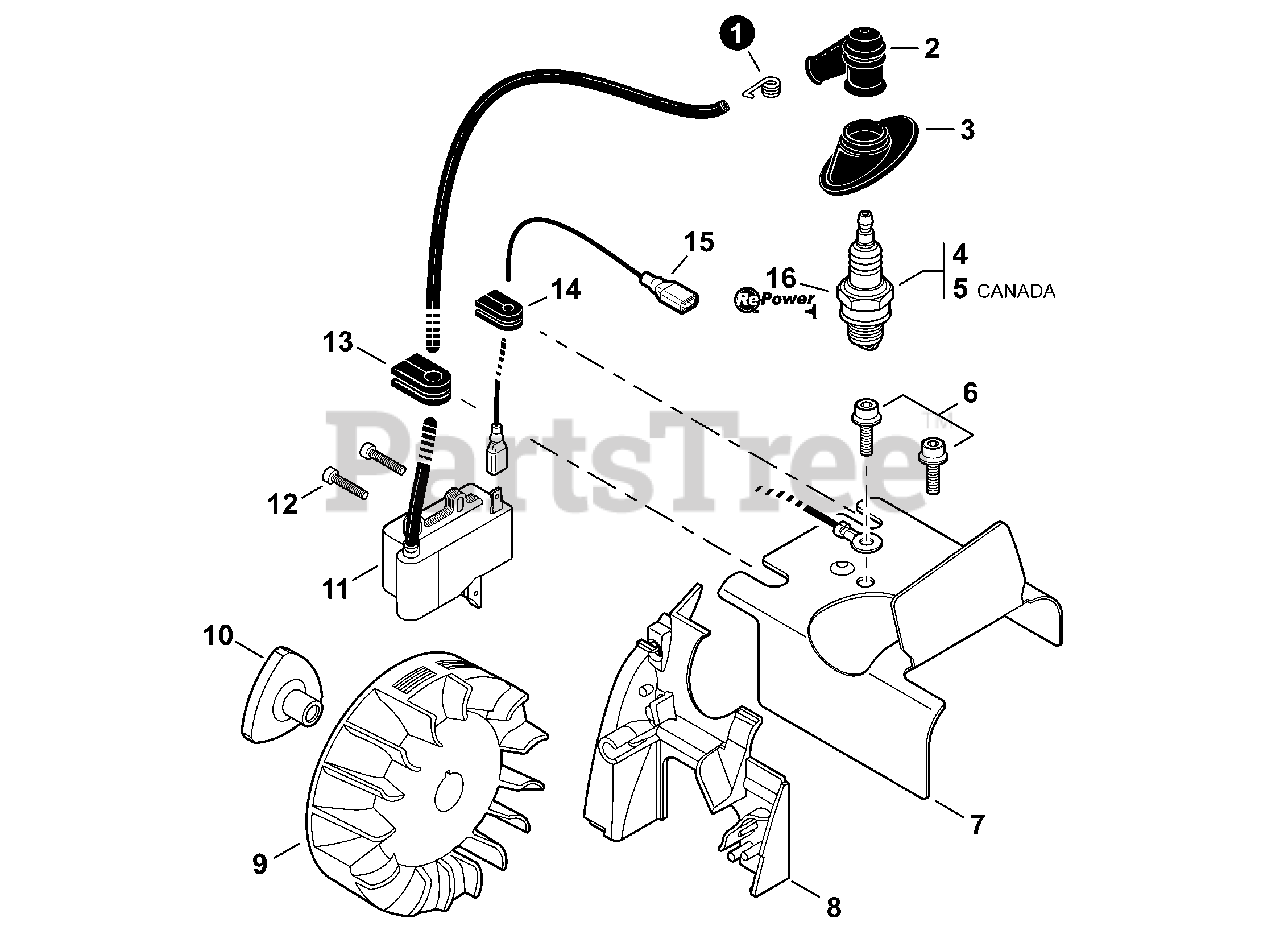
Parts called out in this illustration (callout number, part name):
1	TERMINAL, SPARK PLUG
2	CAP, SPARK PLUG
3	COVER, DUST
4	SPARK PLUG - BPM8Y
5	SPARK PLUG - BPMR8Y
6	BOLT 5×8
7	COVER, CYLINDER
8	COVER, CYLINDER - PLASTIC
9	FLYWHEEL
10	HUB, FAN
11	COIL, IGNITION
12	BOLT 4×20
15	LEAD - IGNITION
16	TUNE-UP KIT - REPOWER
